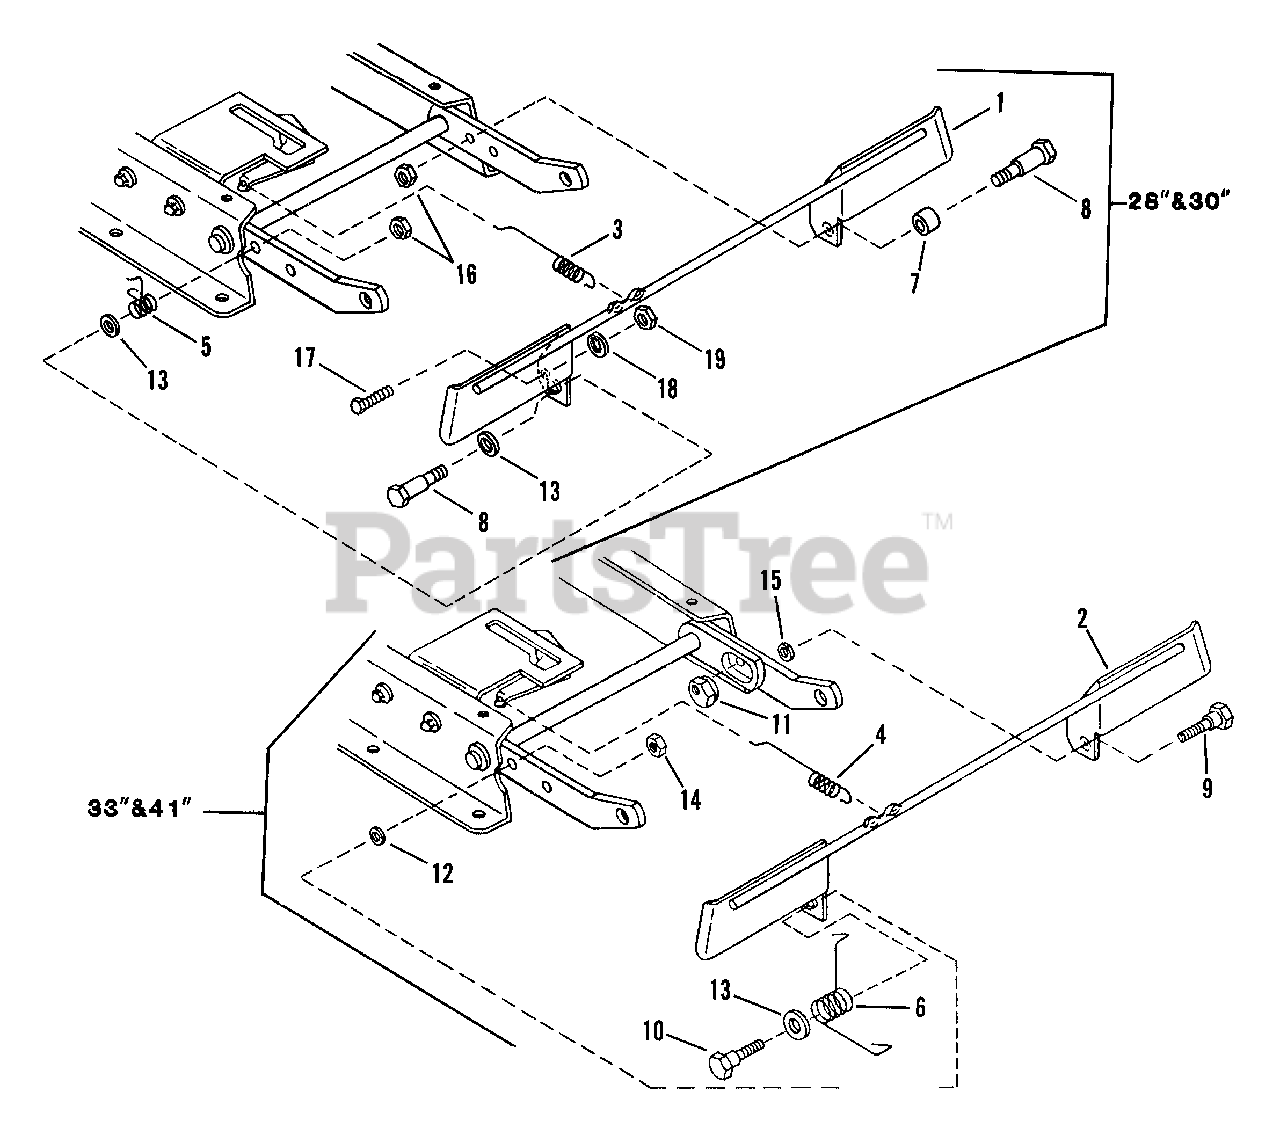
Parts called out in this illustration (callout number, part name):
1	PEDAL, Blade Stop Control (28 & 30")
2	PEDAL, Blade Stop Control (33 & 41 ")
3	SPRING, Latching (28 & 30")
4	SPRING, Latching (33 & 41")
5	SPRING, Pedal (28 & 30")
6	SPRING, Pedal (33 & 41")
7	SPACER (28 & 30")
8	BOLT, 3/8-24 x 1-3/4" Shoulder (28 & 30")
9	BOLT, 3/8-24 x 3/4" Shoulder (33 & 41")
10	BOLT, 3/8-24 x 9/16" Shoulder (33 & 41")
11	ECCENTRIC, Leveling
12	WASHER, 3/8" Flat
13	WASHER, 1/2 Flat
14	NUT, 3/8-24 Hex Center Lock, Grade 5
15	WASHER, 3/8 Internal Tooth Lock
16	NUT, 3/8-24 Hex
17	SCREW, 1/4-28 x 1" Hex Head Cap
18	WASHER, 1/4 Internal Tooth Lock
19	NUT, 1/4-28 Hex
